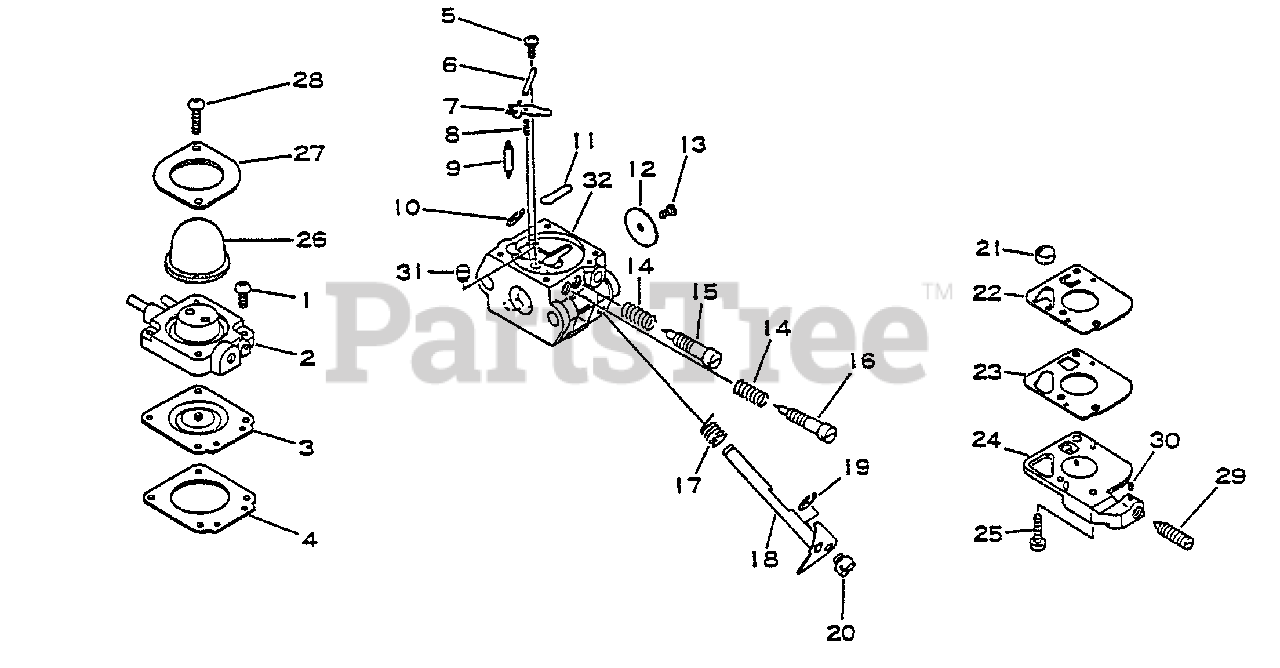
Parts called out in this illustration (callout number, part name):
1	SCREW, PURGE BASE
2	BASE, PURGE
3	DIAPHRAGM
4	GASKET, DIAPHRAGM
5	SCREW
6	PIN, METERING LEVER
7	LEVER, METERING
8	SPRING
9	VALVE, NEEDLE
10	RING, RETAINING
11	PLUG, WELCH
12	VALVE, THROTTLE
15	NEEDLE - MIXTURE
16	NEEDLE - HIGH SPEED
17	SPRING, RETURN
18	SHAFT, THROTTLE
19	RING, RETAINING
21	STRAINER
22	DIAPHRAGM, PUMP
23	GASKET, PUMP
24	BASE, PURGE
25	SCREW, PUMP COVER
26	BULB, PURGE
27	RETAINER, PURGE BULB
28	SCREW, RETAINER
29	SCREW, IDLE ADJUST
30	PIECE, FRICTION
31	NOZZLE, CHECK VALVE
